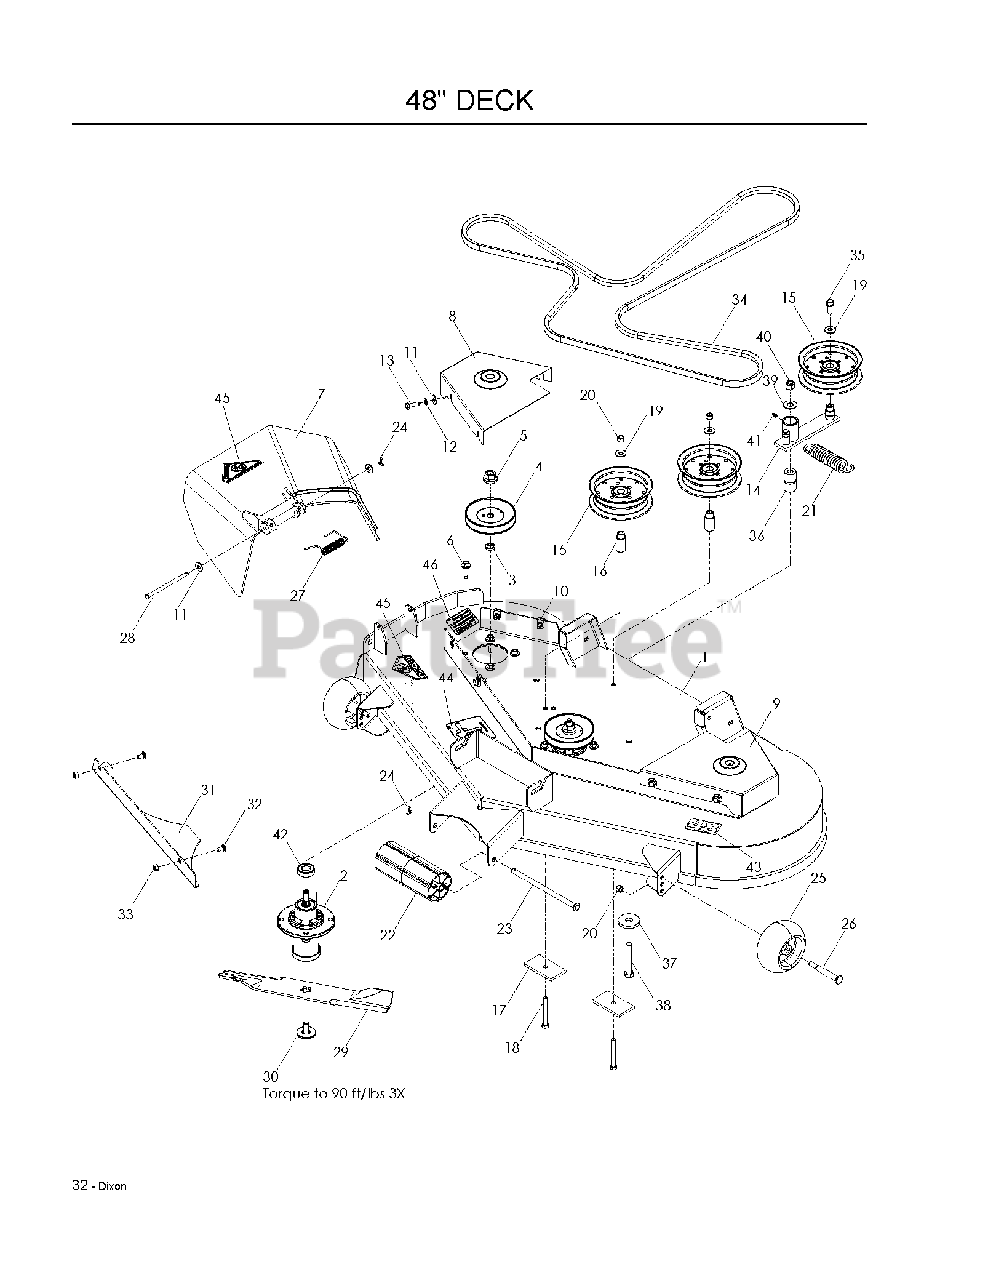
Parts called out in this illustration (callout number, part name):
1	DECK W/DECALS - SZ48
2	MANDREL.DECK.ASSEMBLY
3	WASHER-SPACER
4	PULLEY MANDREL
5	LOCKNUT - 9/16
6	WASHER HEAD SCREW
7	DISCHARGE CHUTE 48"
8	BELTSHIELD - R.H. BLUE
9	BELTSHIELD - L.H. BLUE
10	U-CLIP 5/16-18 NUT RETAINER
11	WASHER 5/16 FLAT
12	WASHER 5/16 LOCK
13	HCS 5/16C X 1
14	PULLEY - IDLER, NYLON
15	PULLEY, IDLER
16	IDLER BUSHING
17	SUPPORT PLATE
18	HCS 3/8C X 3
19	WASHER 3/8 FLAT
20	NUT 3/8-16 NYLOC
22	NOSE ROLLER 48"
23	NOSE ROLLER ROD
24	COTTER PIN 1/8 X 3/4
25	GAUGE WHEEL
26	SHOULDER BOLT 1/2X2-5/8 ZD SPE
27	SPRING - TORSION
28	PIN-CLEVIS 5/16 DIA X 5.19 ZD
29	BLADE, 16-1/4"
30	BLADE BOLT ASSY-7/16" TB REPL
31	Confinement Plate, 48" Black
32	CARRIAGE BOLT 5/16C X 5/8"
33	NUT 5/16 NYLOC
34	BELT, DECK
35	HCS 3/8C X 1 SERRATED HEAD
36	PIVOT BUSHING
37	WASHER, SUPPORT
38	HCS 1/2C X 3 1/4
39	WASHER 1/2 FLAT
40	NUT 1/2-13 HEX NYLOC ZD
41	ZERK
42	BEARING, BALL
43	DECAL, 48"
44	DECAL, BELT ROUTING
45	DECAL, CPSC
46	DECAL, CAUTION
